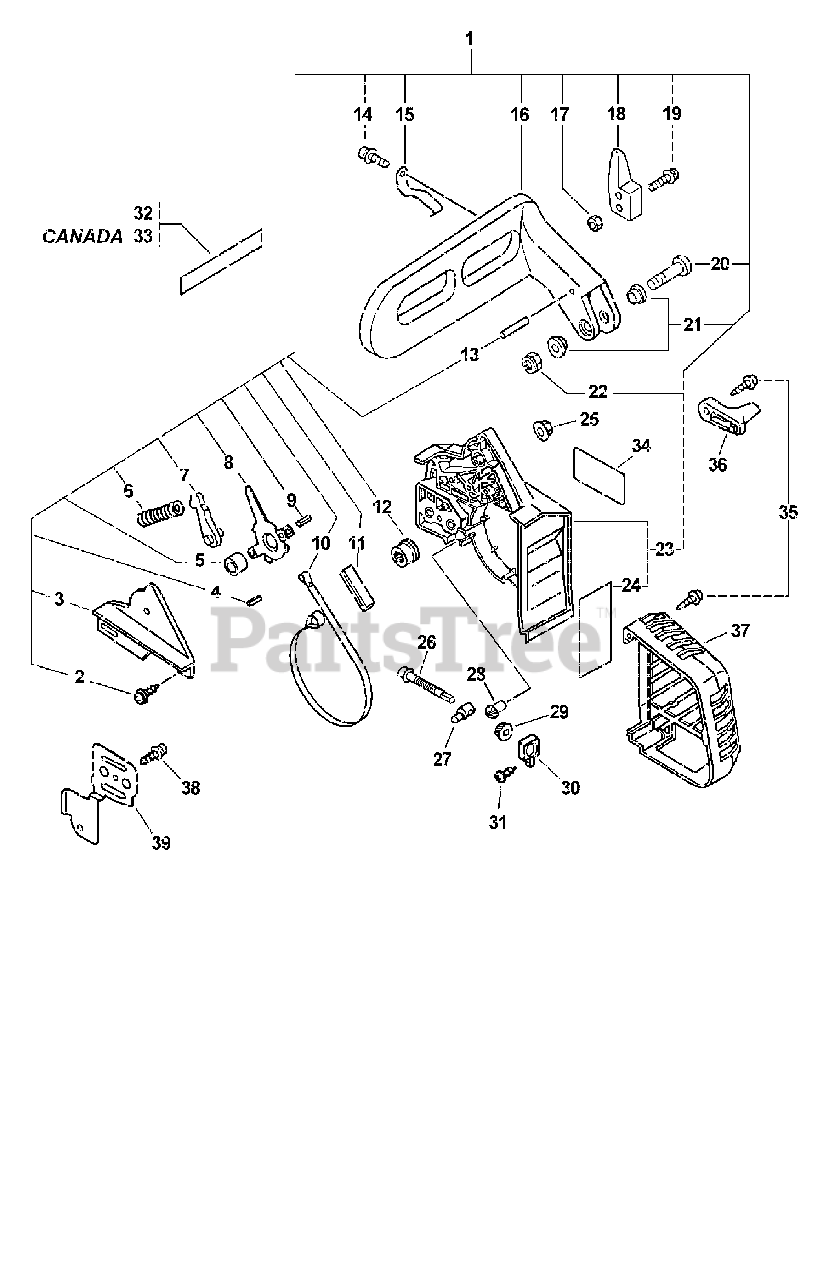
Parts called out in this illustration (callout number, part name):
1	CHAIN BRAKE ASSY
2	SCREW - 4X12 -- TAPPING
3	COVER, BRAKE - GRAY
4	PIN - SPRING -- 2.5X12
5	SPACER - 8
6	SPRING, BRAKE
7	STOPPER, BRAKE
8	LEVER, BRAKE
9	PIN - SPRING -- 4X8
10	BAND, BRAKE
12	ADJUSTER, BRAKE BAND
13	ROLLER - 4X23.8
14	SCREW - 4X12 -- TAPPING
15	SPRING, RETURN
16	LEVER, BRAKE - ORANGE
18	WEIGHT, BRAKE
19	SCREW - 4X22
20	SCREW - 5X32
22	LOCKNUT - 5
23	GUARD, SPROCKET - GRAY
24	DEFLECTOR, HEAT
25	NUT - 6 -- FLANGE
26	SCREW, TENSIONER
27	TENSIONER, CHAIN
28	GEAR - PINION
29	GEAR - BEVEL
30	BRACKET, TENSIONER
31	SCREW - 4X12 -- TAPPING
32	LABEL - BAR & CHAIN
33	LABEL - BAR & CHAIN
34	LABEL - MODEL CS-346
35	SCREW - 5X20 -- TAPPING
36	CATCHER, CHAIN
37	COVER, EXHAUST
38	SCREW - 4X10
39	PLATE, GUIDE - OUTER
